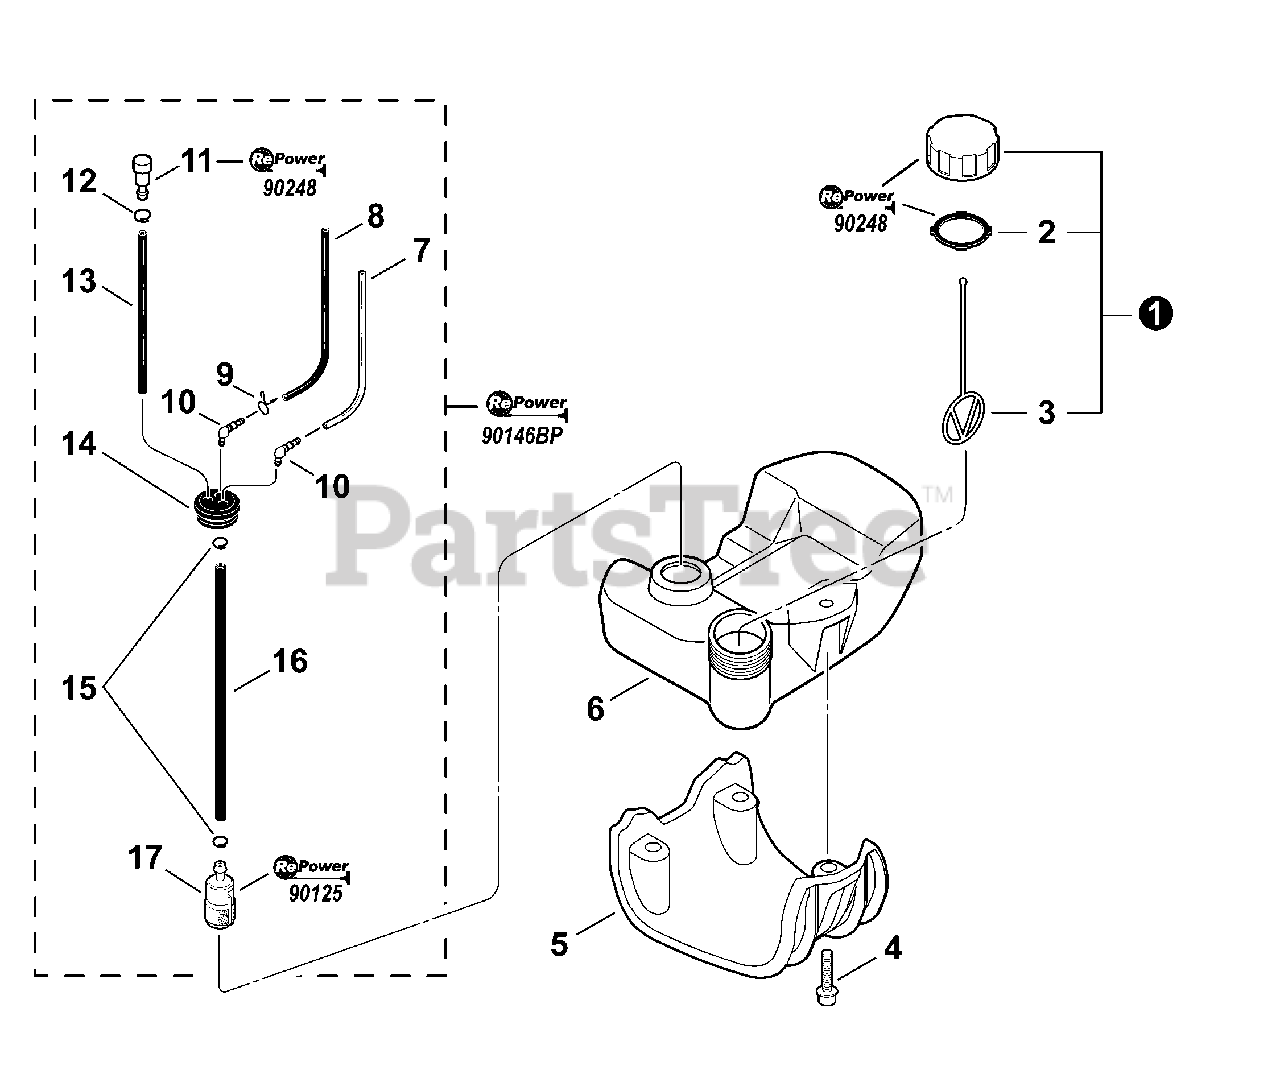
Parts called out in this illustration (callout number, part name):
1	CAP ASY - ORANGE
2	GASKET, CAP
3	CONNECTOR, CAP
4	SCREW - 5×20
6	TANK, FUEL
7	PIPE - 3×6×80 -- CLEAR
8	PIPE - 3×5×87 -- BLACK
9	CLIP - BUTTERFLY
10	CONNECTOR, FUEL PIPE
11	VALVE,CHECK
12	CLIP - 6.5
13	PIPE- 3×6×115 -- BLACK
14	GROMMET, FUEL
15	CLIP - 6
16	PIPE - 3×5×125 -- BLACK
17	FUEL FILTER
